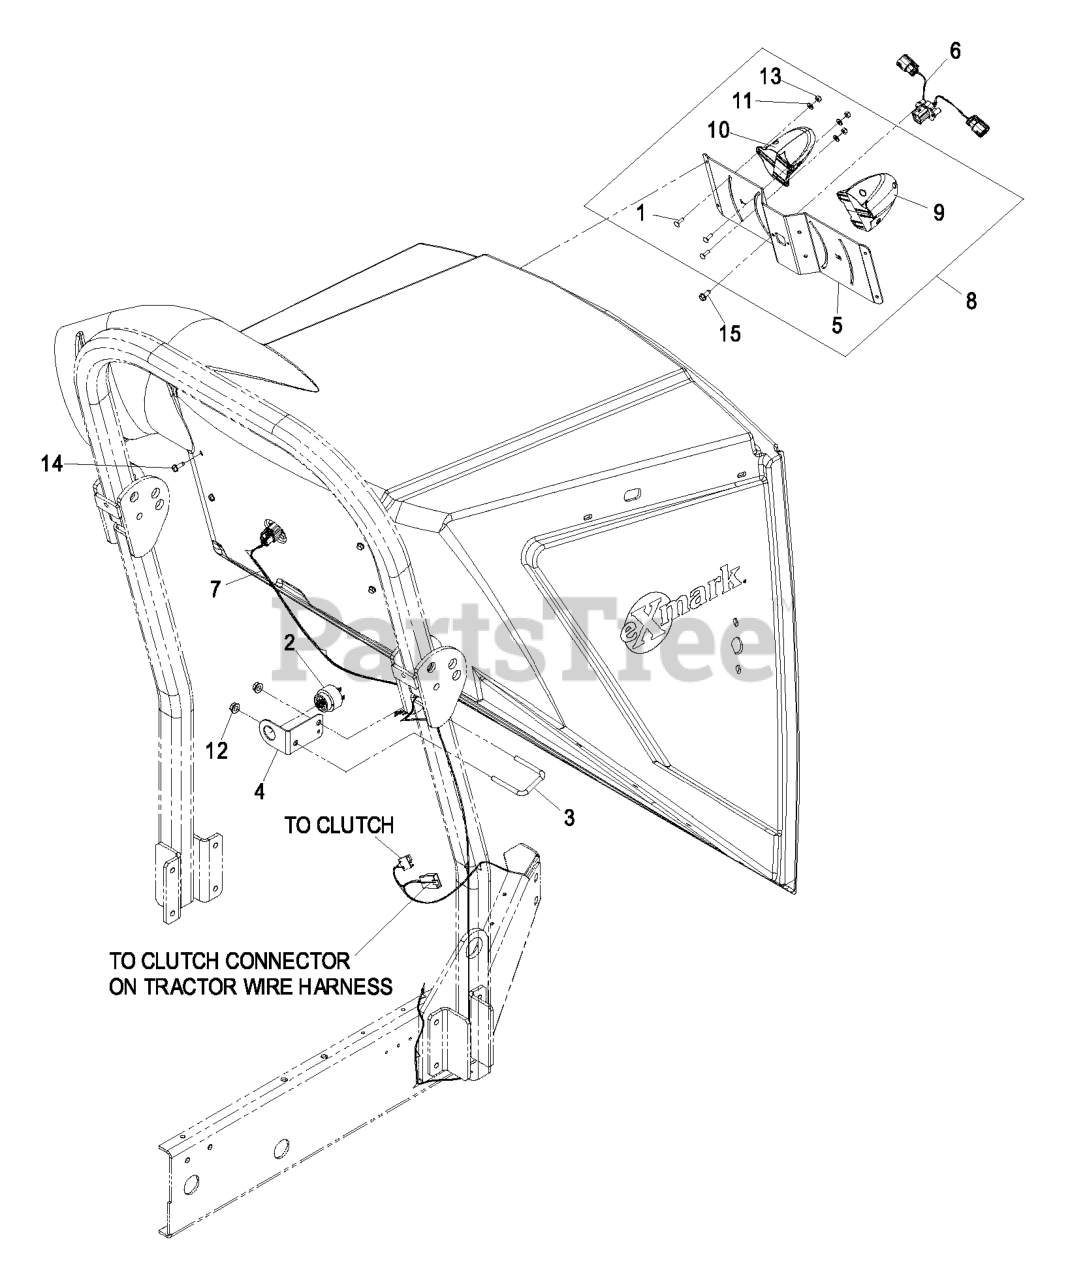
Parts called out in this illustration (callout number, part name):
1	BOLT-CARR
2	ALARM-TONE, DUAL
4	BRACKET,FRUVD ALARM MTG
5	PLATE,FILL SENSOR MTG
6	HARNESS,FRUVD HOPPER
7	HARNESS,FRUVD TRACTOR
8	Asm, Sensor Plate
9	BAG SENSOR ASM
10	BAG SENSOR ASM
11	WASHER-FLAT
12	NUT-HHF, WHIZ
13	NUT-LOCK, NI
14	SCREW-HWH
15	SCREW-PPH
